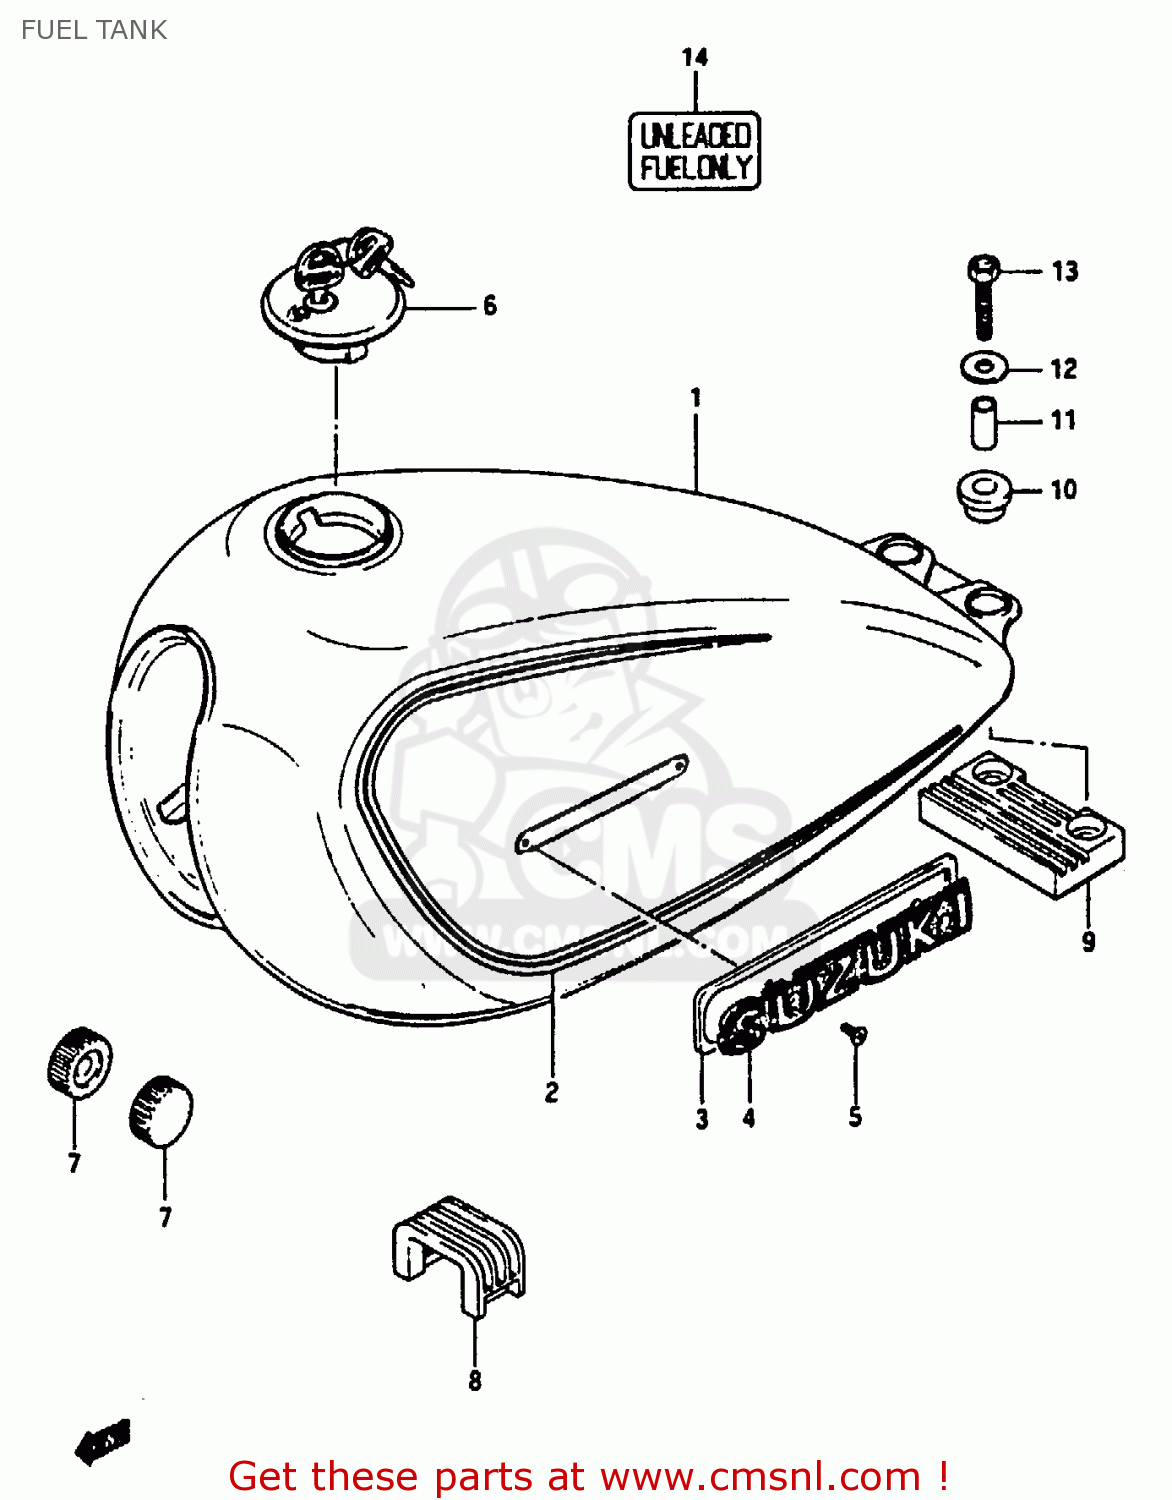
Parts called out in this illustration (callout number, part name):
1	TANK,FUEL (RED)
2	TAPE SET,FUEL TANK
3	CUSHION
4	EMBLEM,FUEL TANK
5	SCREW
6	CAP SET,FUEL TANK
7	CUSHION
8	CUSHION,TANK UPR FR
9	CUSHION,TANK RR NO.1
10	CUSHION
11	SPACER(6.5X10.5X22.5)
12	WASHER(6,5X22X1.6)
13	BOLT(6X35)
14	LABEL,FUEL CAUTION
